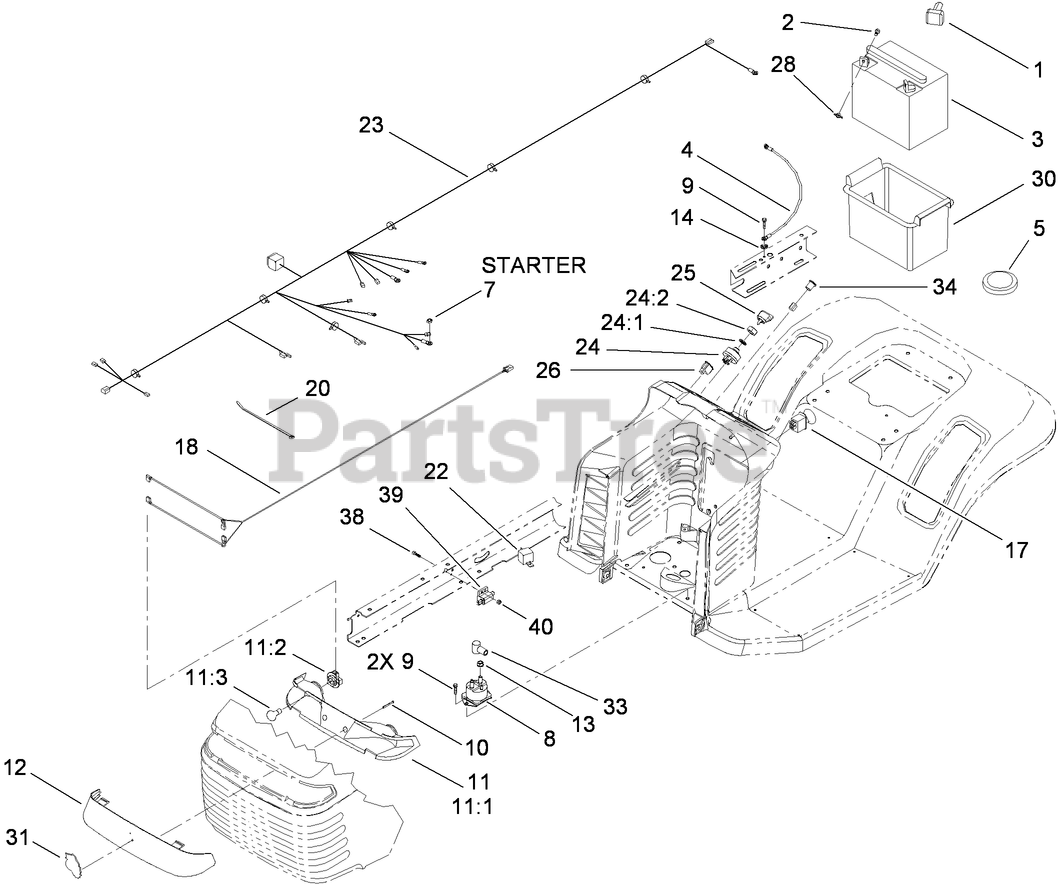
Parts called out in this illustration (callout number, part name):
1	BOOT-TERMINAL
2	SCREW-HH
4	WIRE ASM
5	SWITCH-SEAT
7	NUT-KEPS
8	SOLENOID-STARTER
9	SCREW-HWH
11	HEADLIGHT REFLECTOR ASM
11:1	REFLECTOR-LIGHT
11:2	SOCKET-HEADLIGHT
11:3	BULB
12	LENS-HEADLIGHT
13	NUT-KEPS
14	WASHER-LOCK/EXT
17	SWITCH-PTO,ON-ON-NONE
18	HARNESS-HEADLIGHT
20	TIE-CABLE
22	RELAY
23	HARNESS-WIRE
24:1	WASHER-LOCK
24:2	NUT-HH
25	KEY-IGNITION
26	SWITCH-ROCKER
28	NUT-WING
30	BOX-BATTERY
31	EMBLEM
33	BOOT-INSULATOR, TERMINAL
34	LIGHT-INDICATOR
38	SCREW-HSH
40	NUT-LOCK, NI
